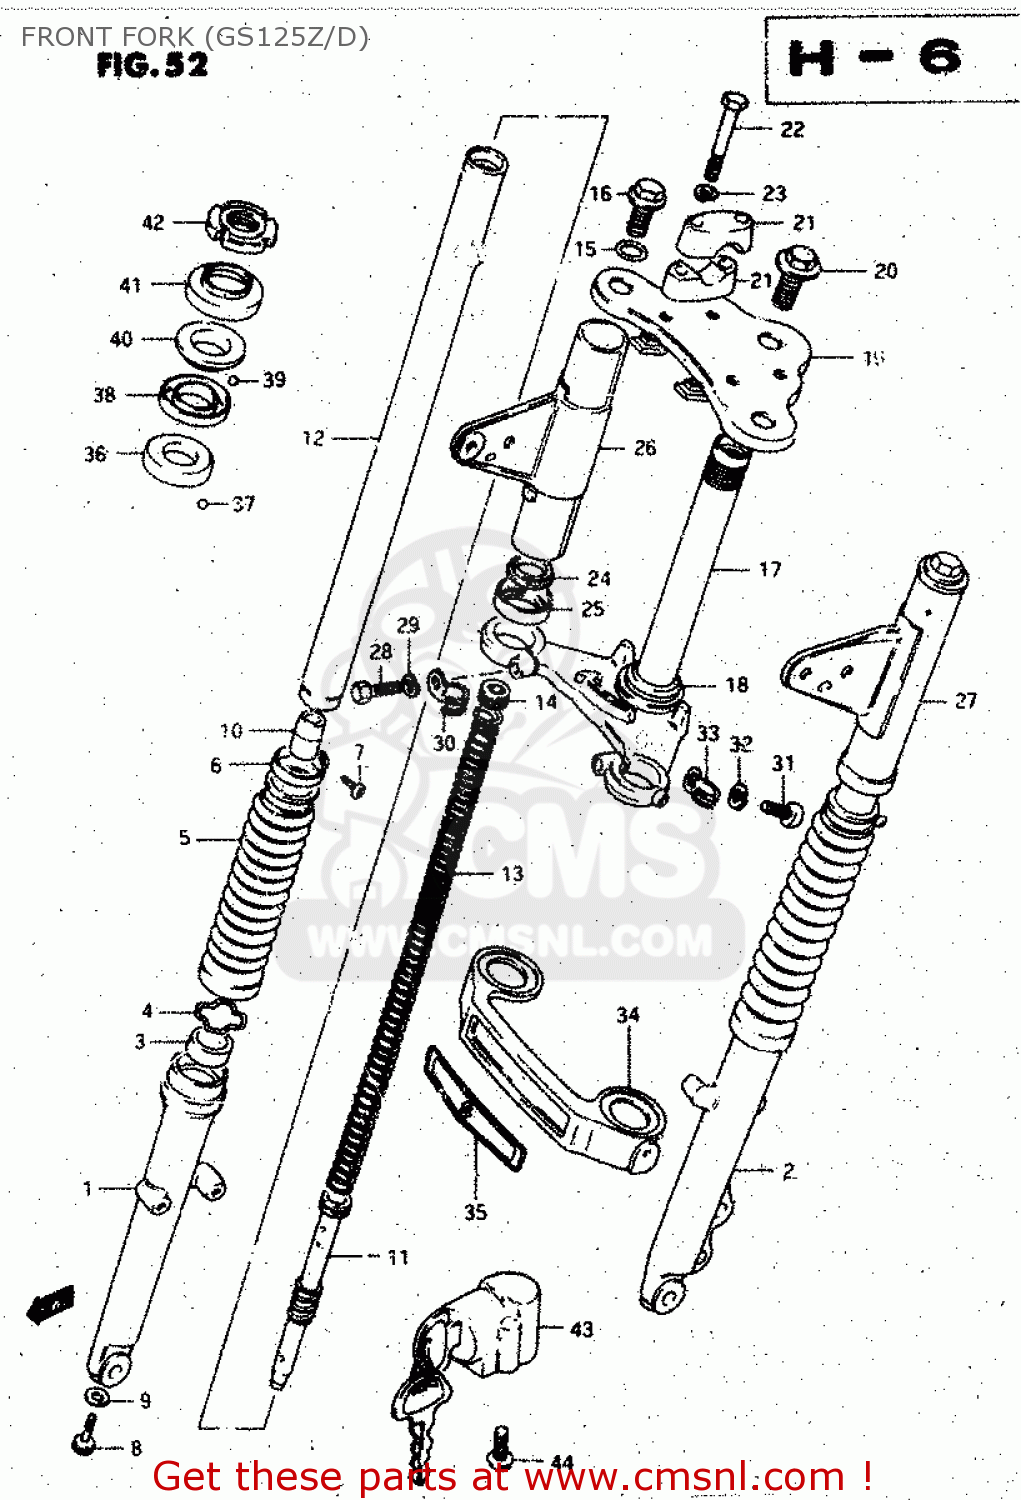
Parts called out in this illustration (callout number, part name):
1	TUBE,OUTER,R
2	TUBE,OUTER,L
3	OIL SEAL,FRONT FORK
4	RING,SNAP
5	BOOT
6	BAND,BOOT
7	SCREW
8	BOLT,FORK CYLINDER(10X25)
9	GASKET (NAS)
10	PIECE,OIL LOCK
11	FRONT FORK DAMPER TUBE
12	TUBE, INNER
13	SPRING
14	NUT
15	O RING
16	CAP
17	STEM, STEERING
18	RACE,STEERING OUTER LWR
19	HEAD,STEERING STEM
20	BOLT
21	HOLDER,HANDLE UPR
22	BOLT
23	LOCK WASHER
24	CUSHION,HEAD LAMP BRACKET
25	GUIDE,BRACKET
26	BRACKET,HEADLAMP,R
27	BRACKET,HEADLAMP,L
28	BOLT,FR FORK LWR(12X33)
29	WASHER,LOCK 12
30	CLIP
31	SCREW
32	WASHER,LOCK
33	CLIP,BRAKE CABLE
34	COVER, FRONT FORK
35	EMBLEM,FR FORK COVER
36	LACE,STEERING INNER LWR
37	BALL
38	RACE,STEERING INNER UPR
39	BALL
40	RACE,STEERING OUTER UPR
41	DUST SEAL,STEERING UPR
42	NUT,STEERING STEM(25X44X10)
43	LOCK ASSEMBLY,STEERING
44	SCREW
